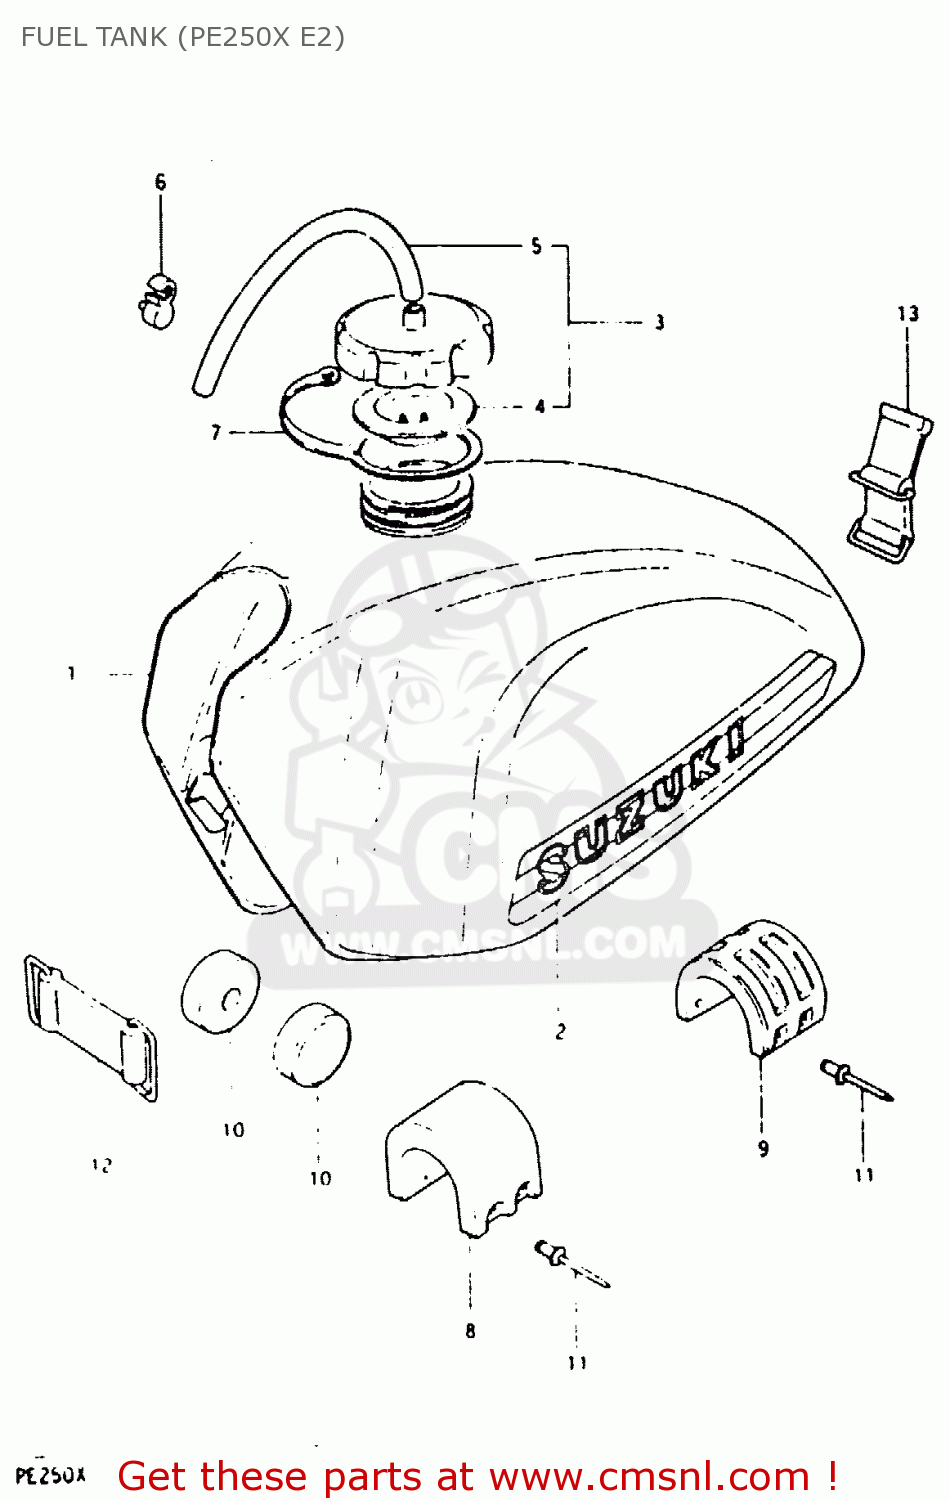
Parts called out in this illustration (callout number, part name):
1	TANK, FUEL (YELLOW)
2	TAPE SET,FUEL TANK
3	CAP ASSEMBLY,FUEL TANK
4	GASKET,FUEL TANK CAP (NAS)
5	HOSE
6	CLAMP,BREATHER HOSE
7	BAND
8	CUSHION, UPPER FRONT
9	CUSHION,FUEL TANK,CENTER
10	CUSHION
11	RIVET
12	BAND
13	BNAD, REAR
